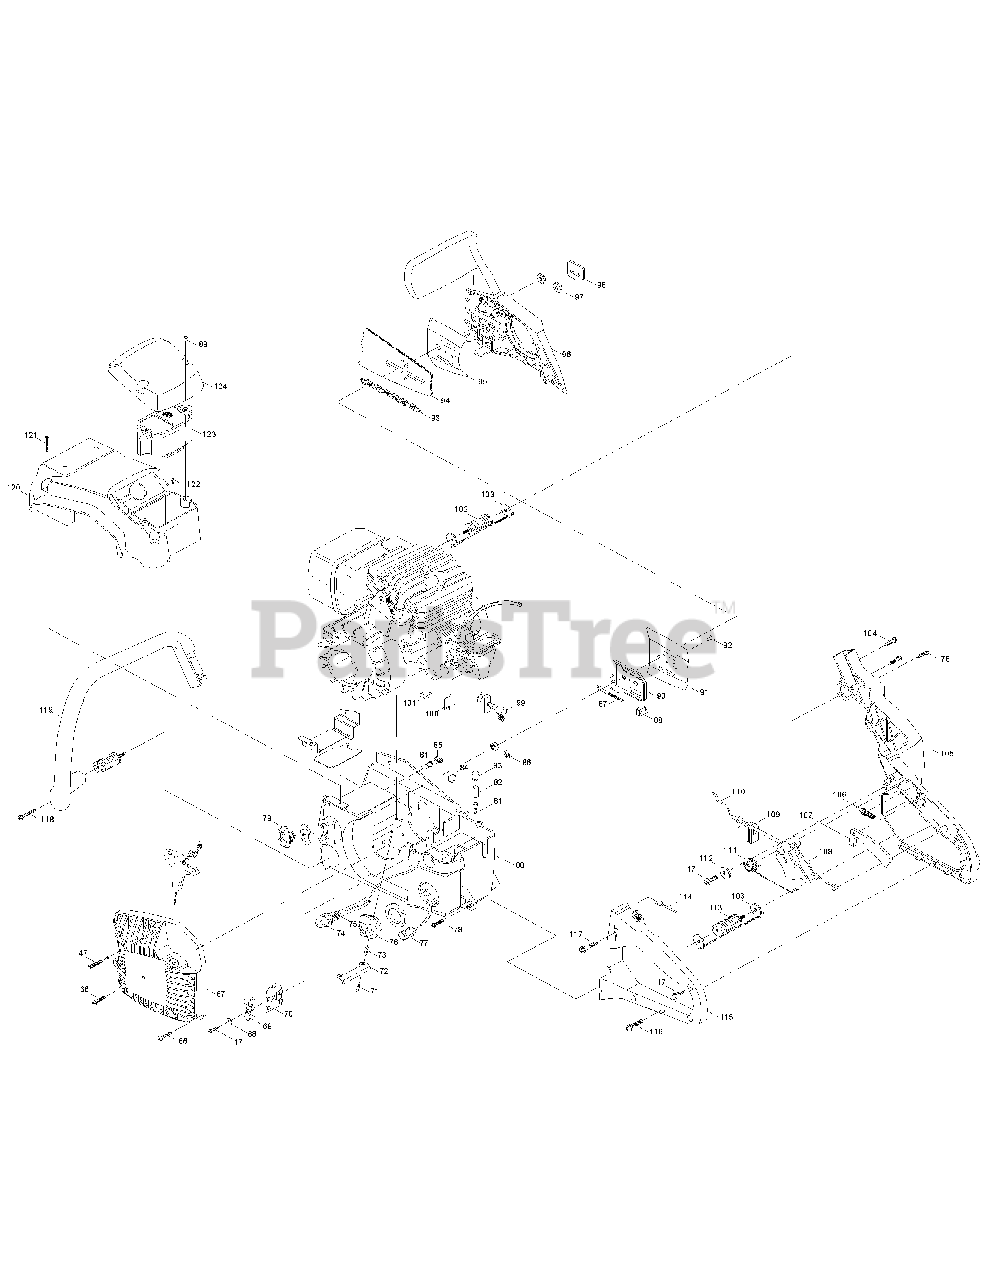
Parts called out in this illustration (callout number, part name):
8	CRANKCASE LOWER
10	C'SHAFT/C'ROD ASS'Y
13	GEAR, WORM
16	PUMP ASS'Y
20	FRUM SPRKT ASS'Y
21	CLUTCH ASS'Y
23	CRANKCASE UPPER
24	FITTING, PULSE LINE
26	CLAMP, WIRE HOSE
27	CONDUIT, FLEX
32	RING, PISTON
35	IGNITION ASS'Y
38	SCREW
39	FLANGE
42	SPARK PLUG
46	MUFFLER BODY ASS'Y
51	COVER, MUFFLER
52	LOCKPLATE
54	BOOT, CARBURETOR
59	CARBURETOR
67	STARTER ASS'Y
74	PRIMER, REMOTE
76	CAP, FUEL
77	FILTER, FUEL
80	FUEL/OIL TANK ASS'Y
81	VALVE DUCKBILL
90	PLATE, BAR
91	PLATE, FLANGE
96	CHAIN BRAKE ASS'Y
99	CKOKE ASS'Y
100	ROD, CHOKE
102	ISOLATOR ASS'Y
103	CABLE ASS'Y
105	FRAME, REAR
107	RELEASE, TRIGGER
113	ISOLATOR ASS'Y
114	WIRE ASS'Y
115	COVER ASS'Y, HANDLE
119	HANDLE ASS'Y
120	COVER ASS'Y
123	AIR CLEANER ASS'Y
126	CARRY CASE
